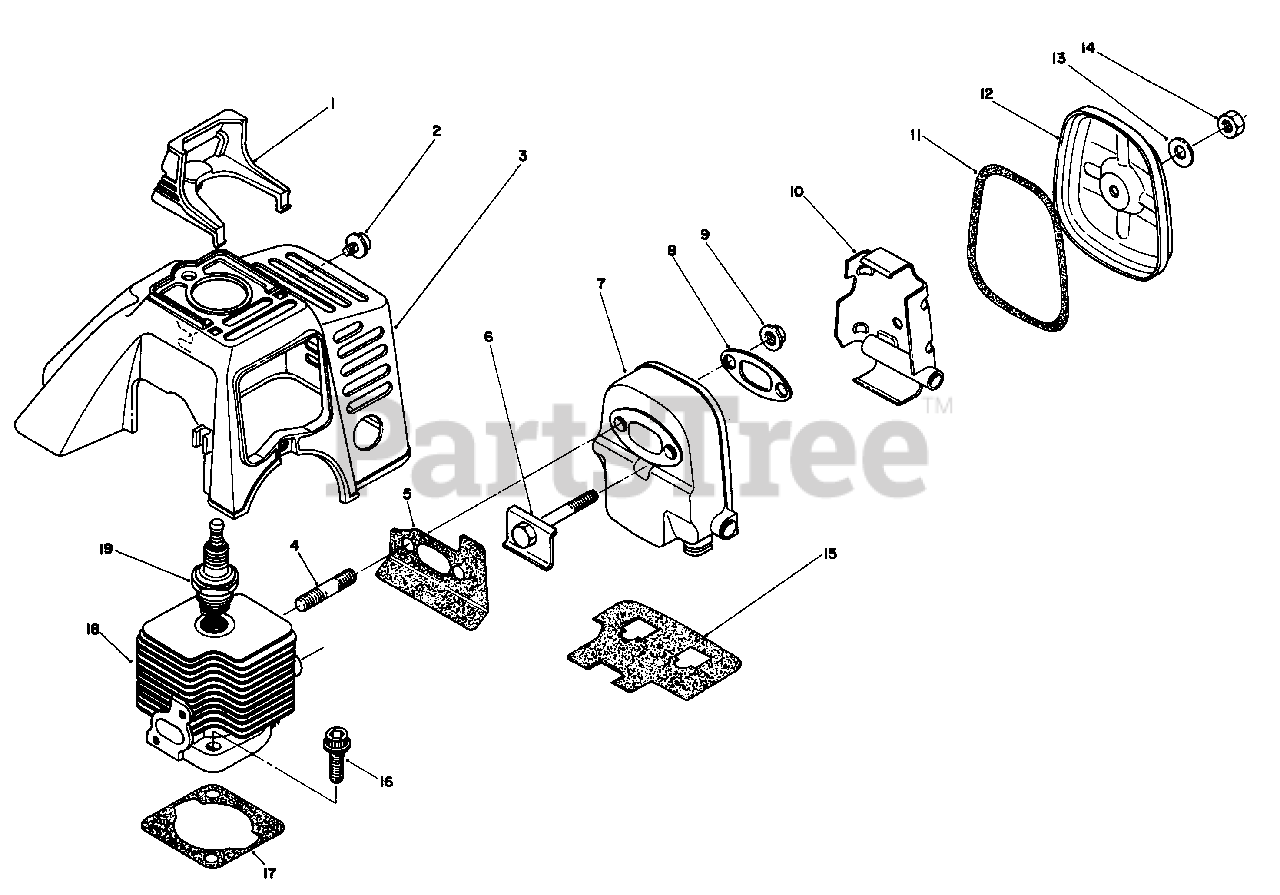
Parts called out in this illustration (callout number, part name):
1	Guard, Spark Plug
2	Screw & Washer
3	Cover, Top
4	Bolt, Stud
5	Gasket, Muffler
6	Bolt, Muffler Body
7	Body, Muffler
9	Nut, Conical Spring
11	Gasket, Muffler Seal
12	Lid, Muffler
13	Washer, Gasket
15	Gasket
16	Bolt, Flange
17	Gasket, Cylinder
18	Cylinder
19	Plug, Spark
